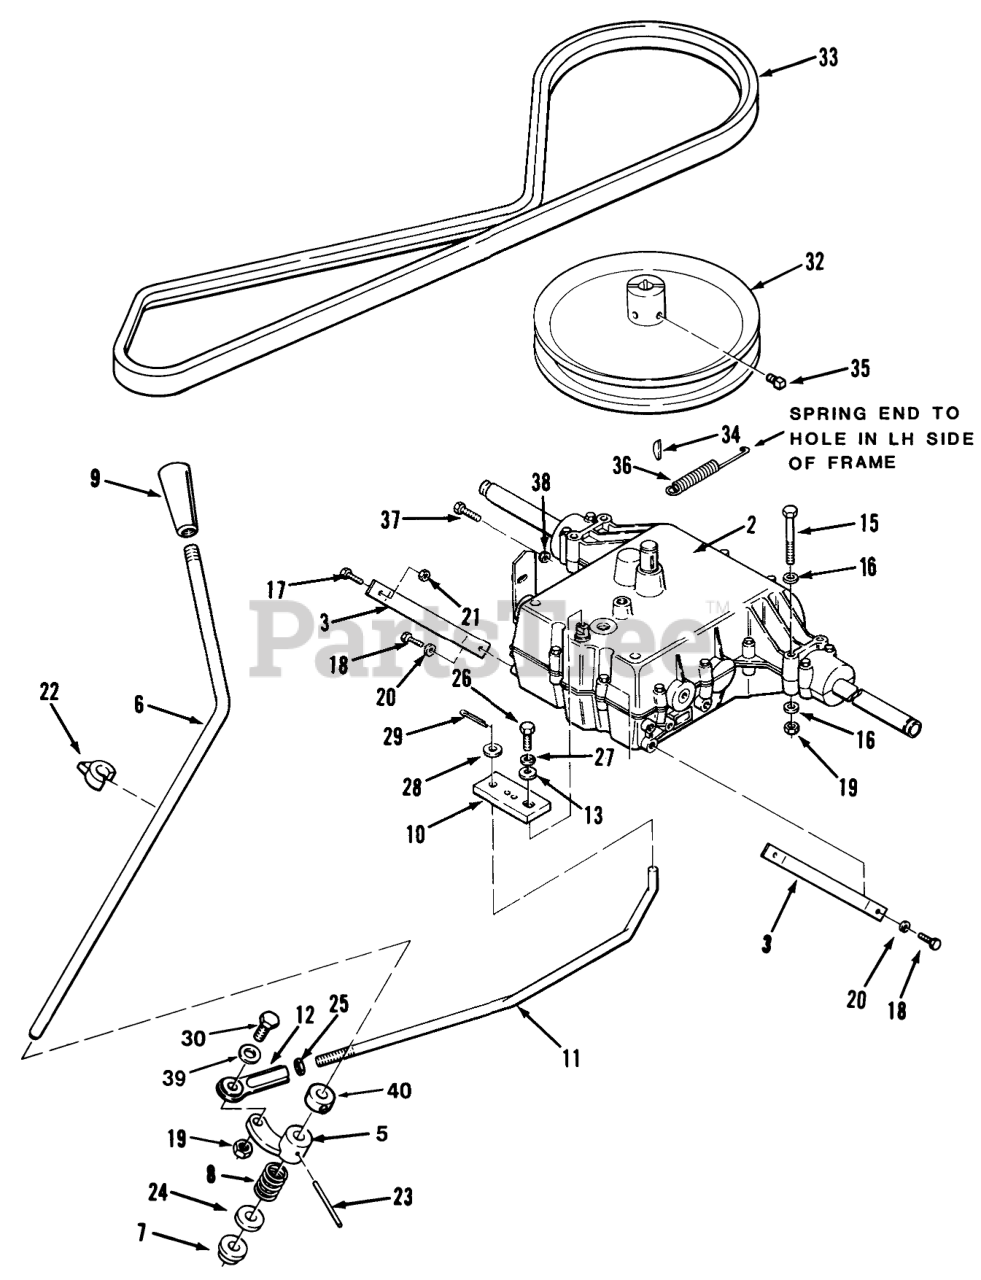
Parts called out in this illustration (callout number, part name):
2	ASS'Y TRANSAXLE 5-SP
3	TORQUE-STRAP R
5	ARM SHIFTER B
6	ROD-SHIFT LEVER
7	BUSHING-NYLINER
8	SPRING COMPRESSION
10	ARM-TRANSMISSION 5SP
11	ROD-LINKAGE
12	END-ROD
13	WASHER
15	SCREW-HH
16	WASHER-PLAIN
17	CARRIAGE BOLT -4
18	Screw
19	NUT-LOCK, NI
20	WASHER-LOCK
21	Nut
22	POINTER
23	SPIROL PIN 7/32X21/2
24	SHIM-WASHER
25	NUT-JAM
26	SCREW-HH
27	WASHER-LOCK
28	WASHER-SPECIAL
29	PIN-COTTER
30	SCREW-HH
32	PULLEY-TRANS (L)
33	BELT-V
34	KEY-HI-PRO
35	SCREW-SQH
36	SPRING-EXTENSION
37	SCREW-HH
38	Nut
39	WASHER-PLAIN
40	COLLAR
